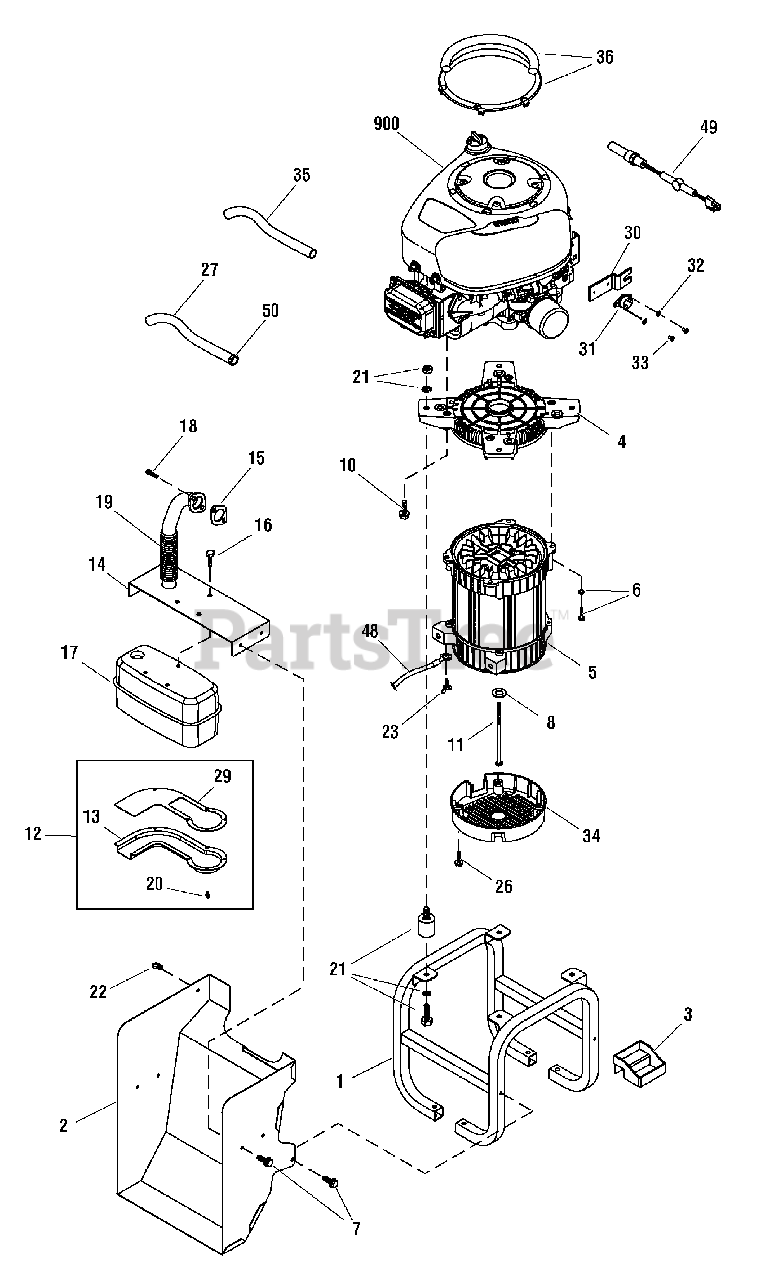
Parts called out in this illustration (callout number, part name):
3	TRAY, Oil Drain
4	ADAPTER, Engine
5	ALTERNATOR, Complete
6	KIT, Hardware Adapter
7	BOLT
10	TAPTITE
11	CAPSCREW, Hex, Head, 5/16-24 x 9-7/8
12	DEFLECTOR, Muffler
14	BRACKET, Muffler
20	KIT, Hardware, Deflector
21	KIT, Vibration Mount
29	ARRESTOR, Spark
30	PLATE, Temp Switch
33	SCREW
34	COVER, Rear Bearing
35	HOSE, Oil Drain
900	** ENGINE
